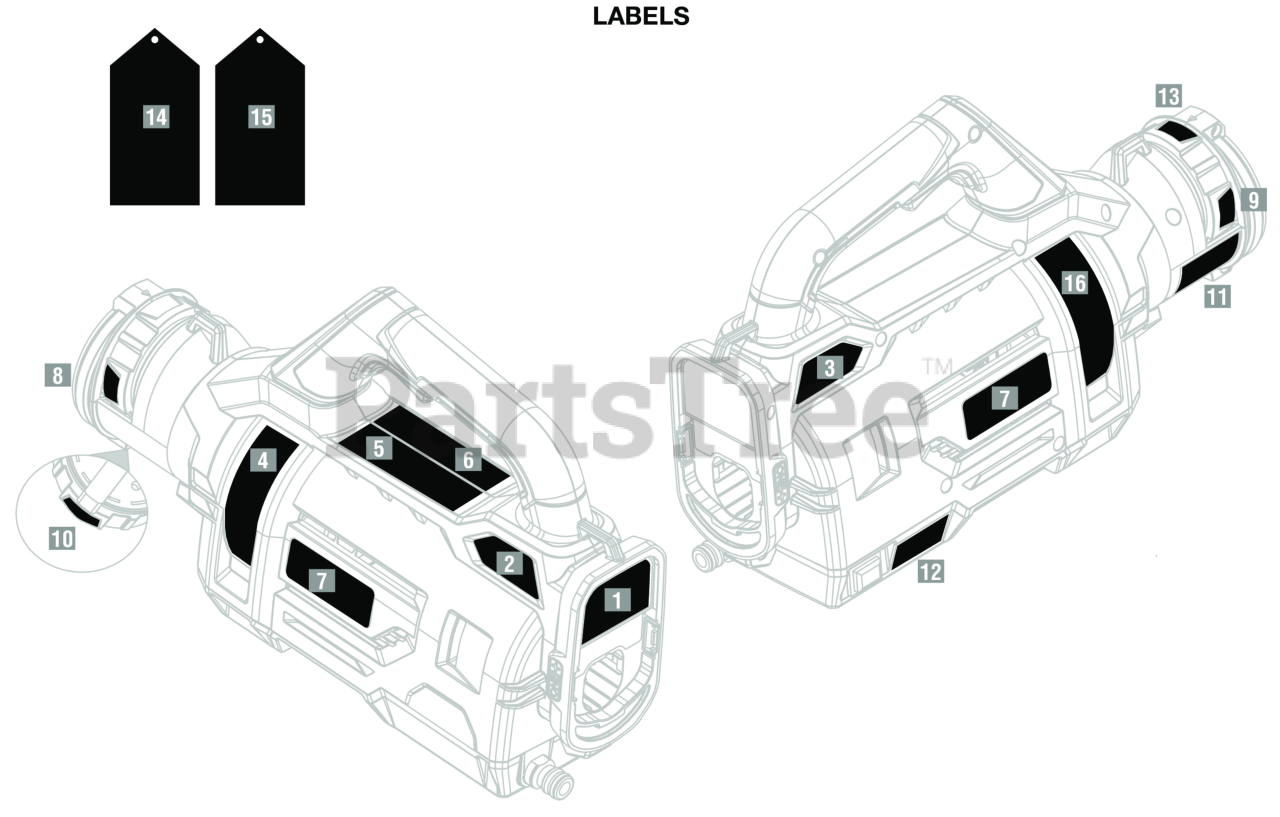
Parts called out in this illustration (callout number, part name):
1	Data Label (Foot)
2	18V Label (Left)
3	18V Label (Right)
4	Electrostatic Logo Label (Left)
5	Warning/Icon Label
6	Warning Label
7	Logo Label
8	High Spray Nozzle Label
9	Low Spray Nozzle Label
10	Medium Spray Nozzle Label
11	Caution Label
12	ES On/Off Label
13	Remove/Eject Puck Label
14	Cleaning Nozzle Reference Guide Hang Tag (EN/FR/SP)
15	Cleaning Nozzle Reference Guide Hang Tag (PORT)
16	Electrostatic Logo Label (Right)
